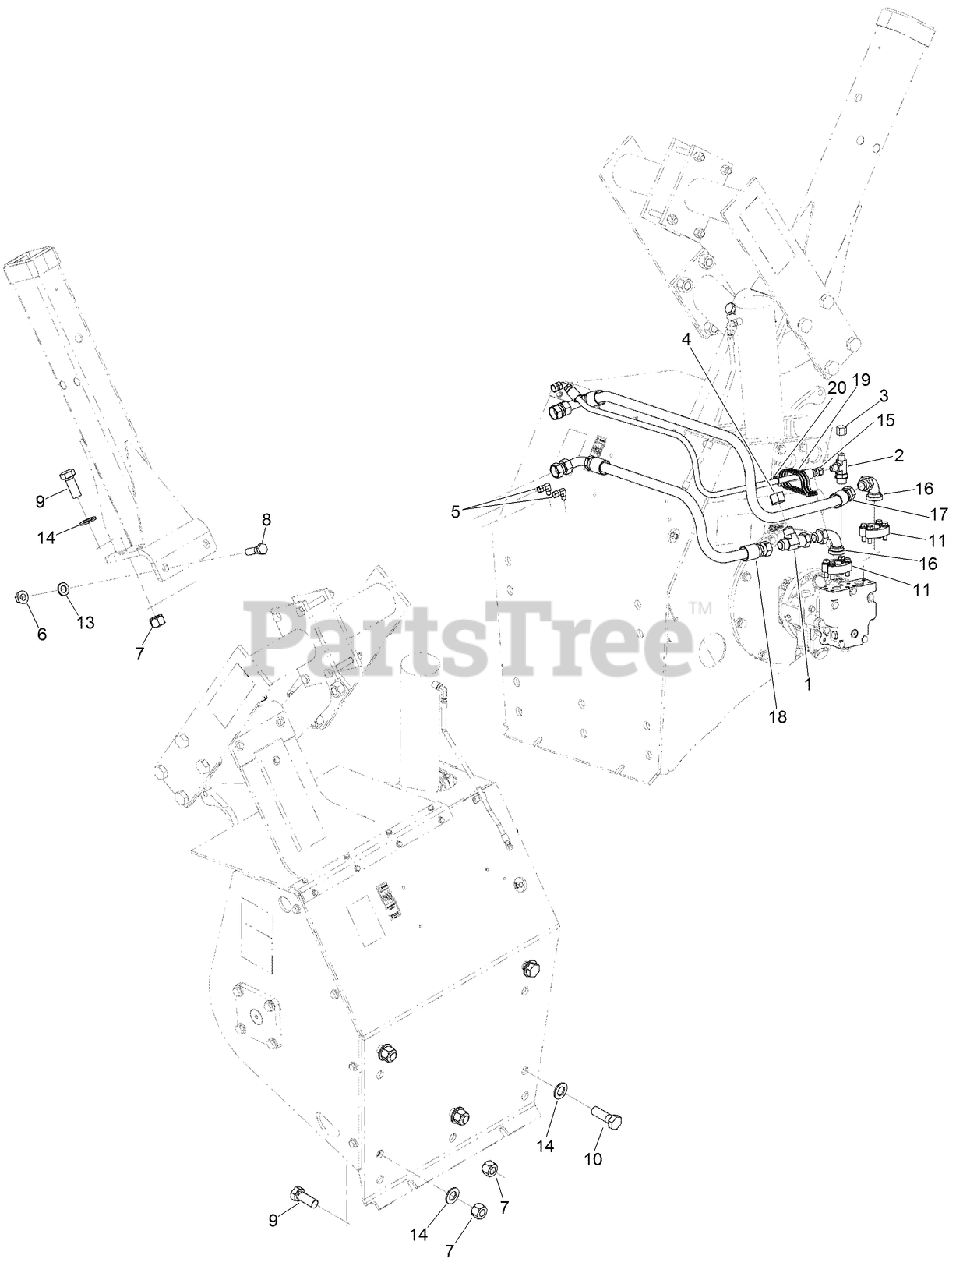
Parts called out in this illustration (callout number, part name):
1	TEE-SWIVEL
2	FITTING-TEE
3	FITTING-CAP
5	ELBOW-SWIVEL, 90 DEG
6	NUT-HEX FLANGE
11	HYD FLANGE KIT
13	WASHER-Flat
15	ASSEMBLY - Hose, Case Drain
16	FITTING-ELBOW
17	HOSE, Hyd, A port ground drive pump (1st pump) to B port ground drive 51 motor
18	ASSEMBLY - Hose, Low Pressure Loop
19	STRAP-TIE
20	STRAP-TIE, NYLON
